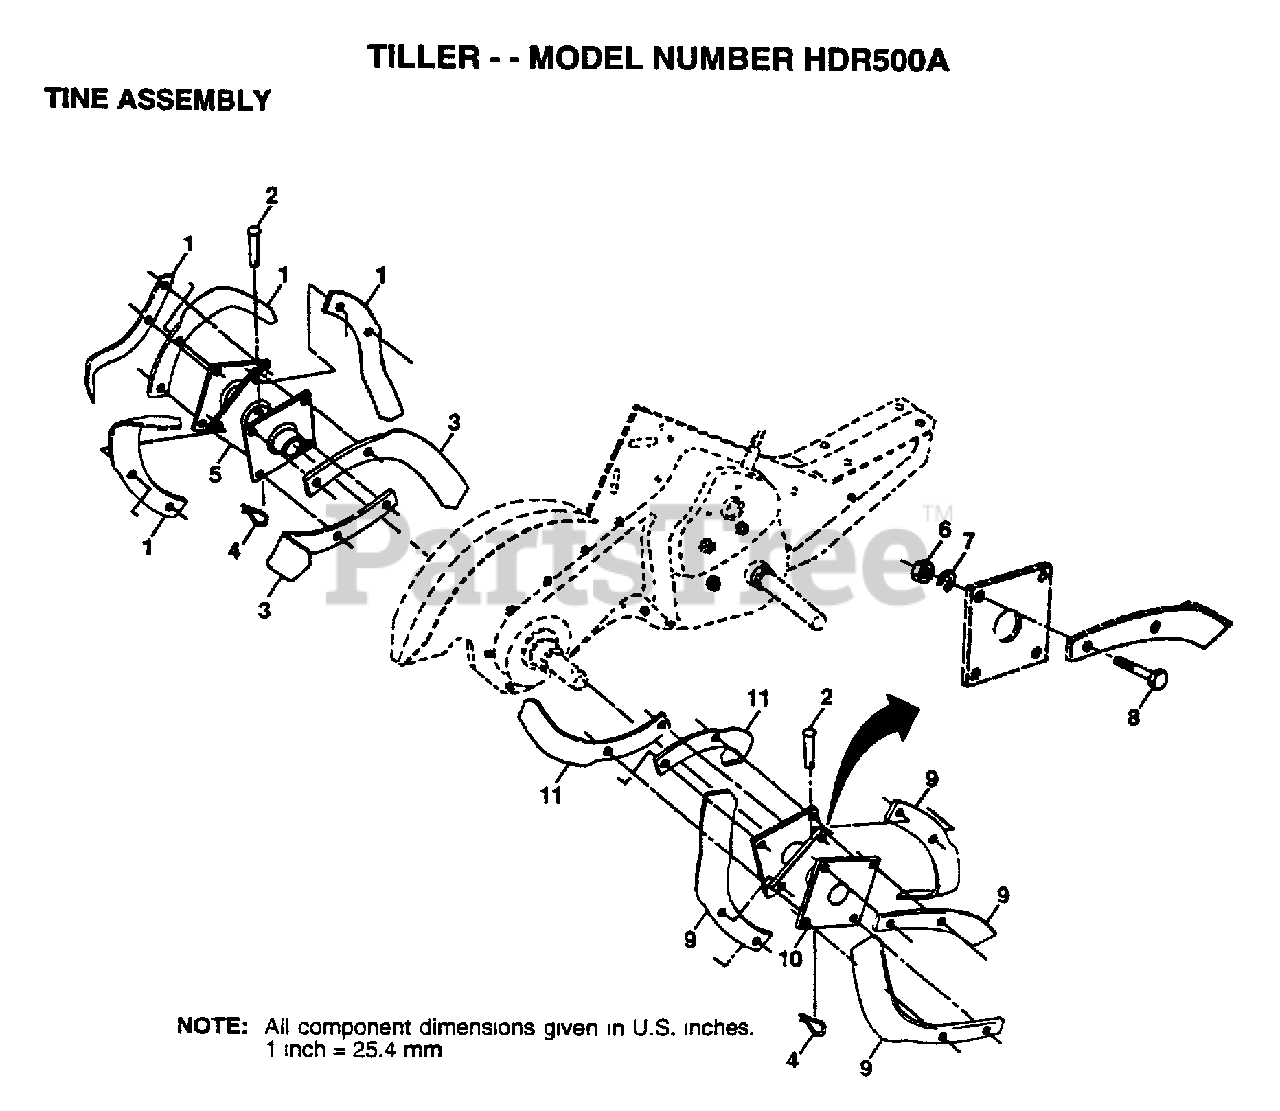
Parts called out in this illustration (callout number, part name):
1	DECAL.PNL.CONTROL
2	DECAL.LOGO.
4	DECAL.INSTRUCTION
5	DECAL TI
6	DECAL CRT
8	DECAL, BRIGGS & STRATTON
9	DECAL TI
